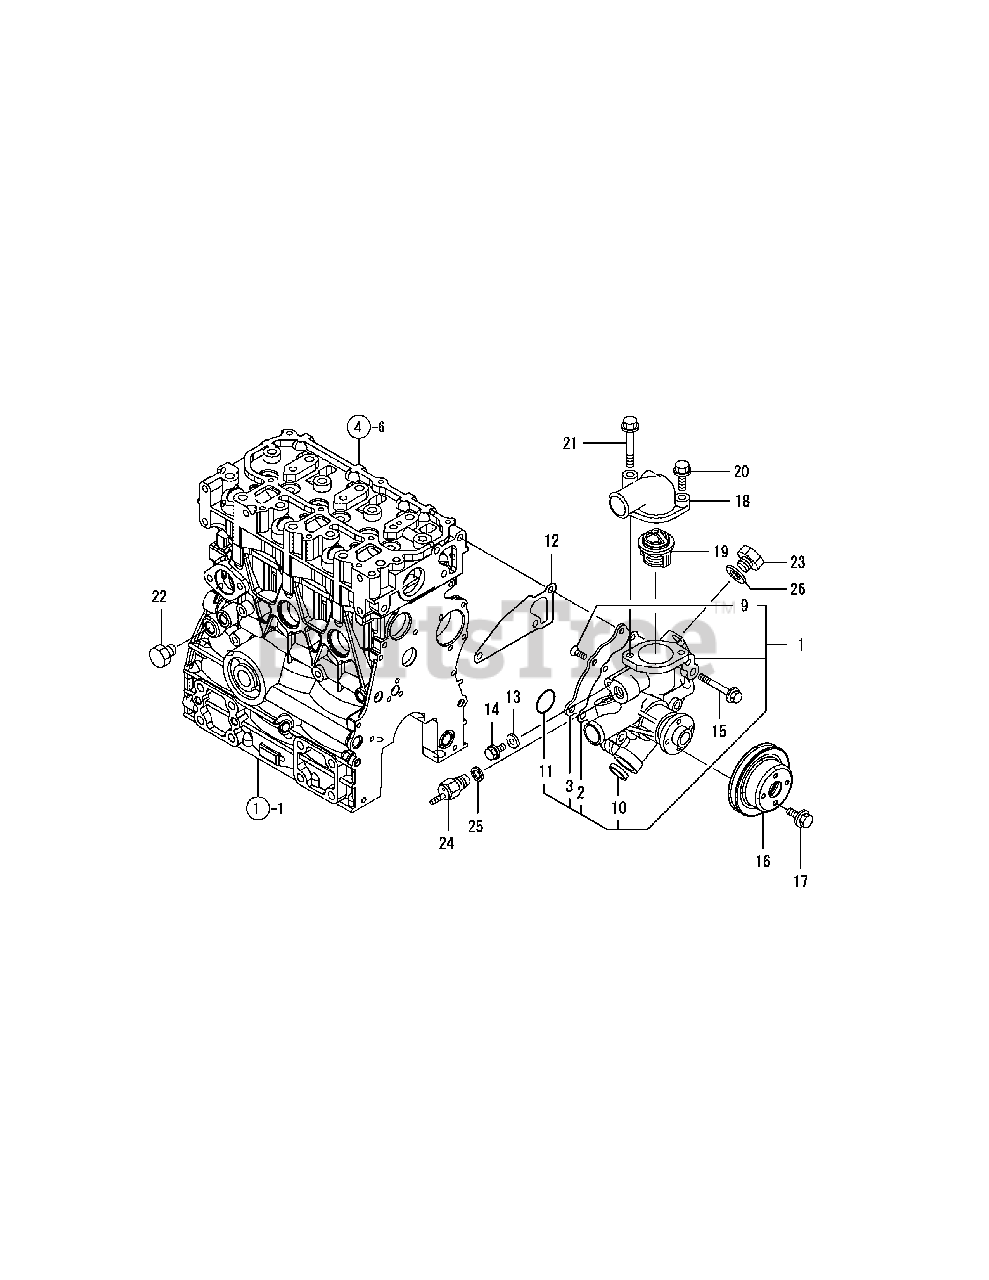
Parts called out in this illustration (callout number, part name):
1	Pump Assembly, Water
9	Screw, M 6 x 12
12	Gasket, Water Pump
13	Gasket 8, Round
14	Bolt, M 8 x 12 Plated
15	Bolt, M 8 x 50 Plated
16	V-Pulley, C.W. Pump
17	Bolt, M 6 x 12 Plated
18	Cover, Thermostat
20	Bolt, M 6 x 25 Plated
21	Bolt, M 6 x 65 Plated
24	Switch, Thermo
